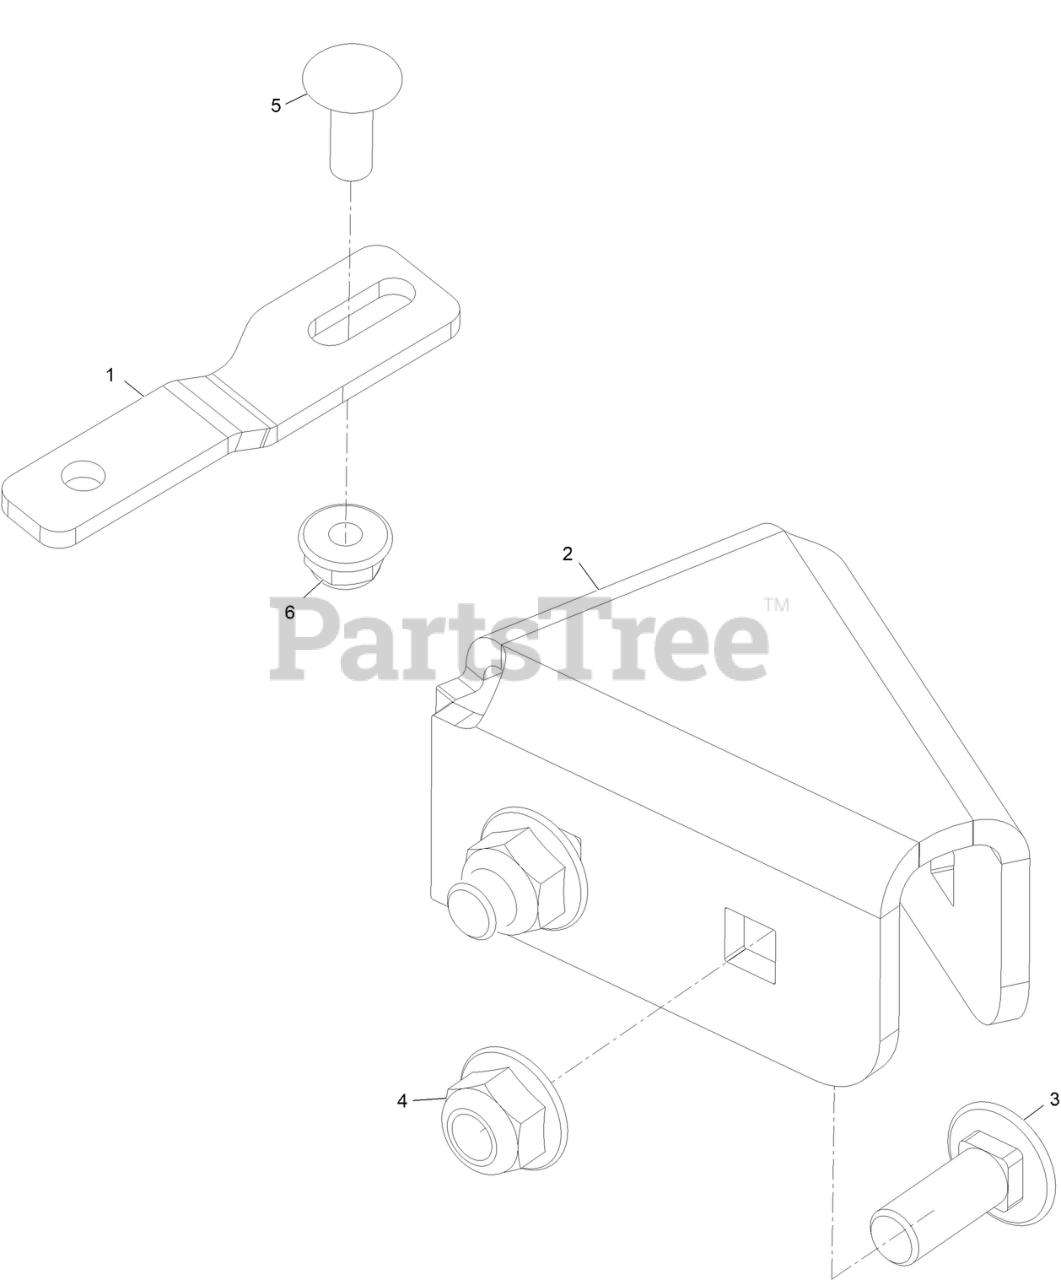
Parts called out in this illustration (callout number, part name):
1	Bracket, Ocdc [red]
2	BRACKET-OCD
3	SCREW-CARR
4	NUT-HF, NI
5	BOLT-CARR
